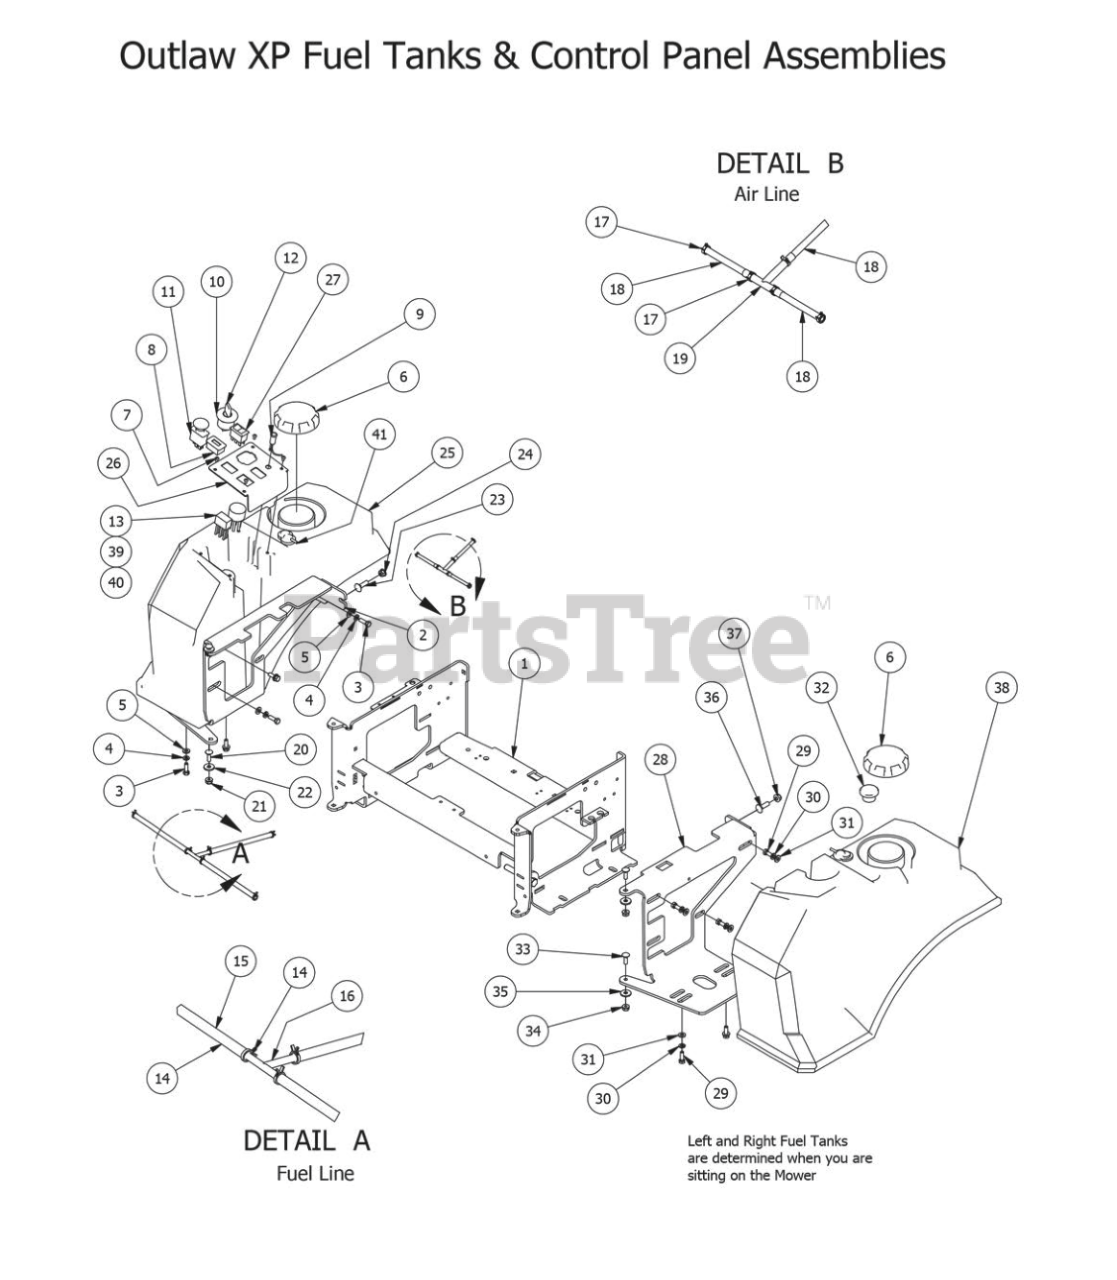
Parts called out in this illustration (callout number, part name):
1	Outlaw Seat Bracket 2012
2	Outlaw Tank Support 2012 (Right)
3	5/16" x 1" Bolt
4	5/16" Lock Washer
5	5/16" Flat Washer
6	3.5" Tethered Fuel Cap
7	10-32 x 3/8" Button Socket Head Bolt
8	Tachometer
10	Ignition Switch
11	PTO Engager
12	Ignition Key
13	Wiring Harness- 852cc kawasaki Outlaw
14	1/4 fuel clamp
15	1/4" fuel line hose
16	fuel line T
17	3/16 vinyl clamp
18	1/4" vinyl tubing
19	fuel line T
20	5/16" x 1" Carriage Bolt
21	5/16-18 Nylon Flange Nut
22	.360 ID Plastic Washer
23	3/8" x 1 1/4" Carriage Bolt
24	3/8" Nylock Flange Nut
25	2012 EPA Fuel Tank - XP-XTRM - Right
26	Outlaw Control Panel (Rocker Switch)
27	Rocker Deck Lift Switch - 2011
28	Tank Support 2012 Outlaw (Left)
29	5/16" x 1" Bolt
30	5/16" Lock Washer
31	5/16" Flat Washer
32	Fuel Gauge-Tanks w/downtube
33	5/16" x 1" Carriage Bolt
34	5/16-18 Nylon Flange Nut
35	.360 ID Plastic Washer
36	3/8" x 1 1/4" age Bolt
37	3/8" Nylock Flange Nut
38	2012 EPA Fuel Tank- XP-XTRM- Left
39	Wiring Harness 993cc Vanguard Outlaw
40	Relay Terminal
41	Rollover Valve-White
